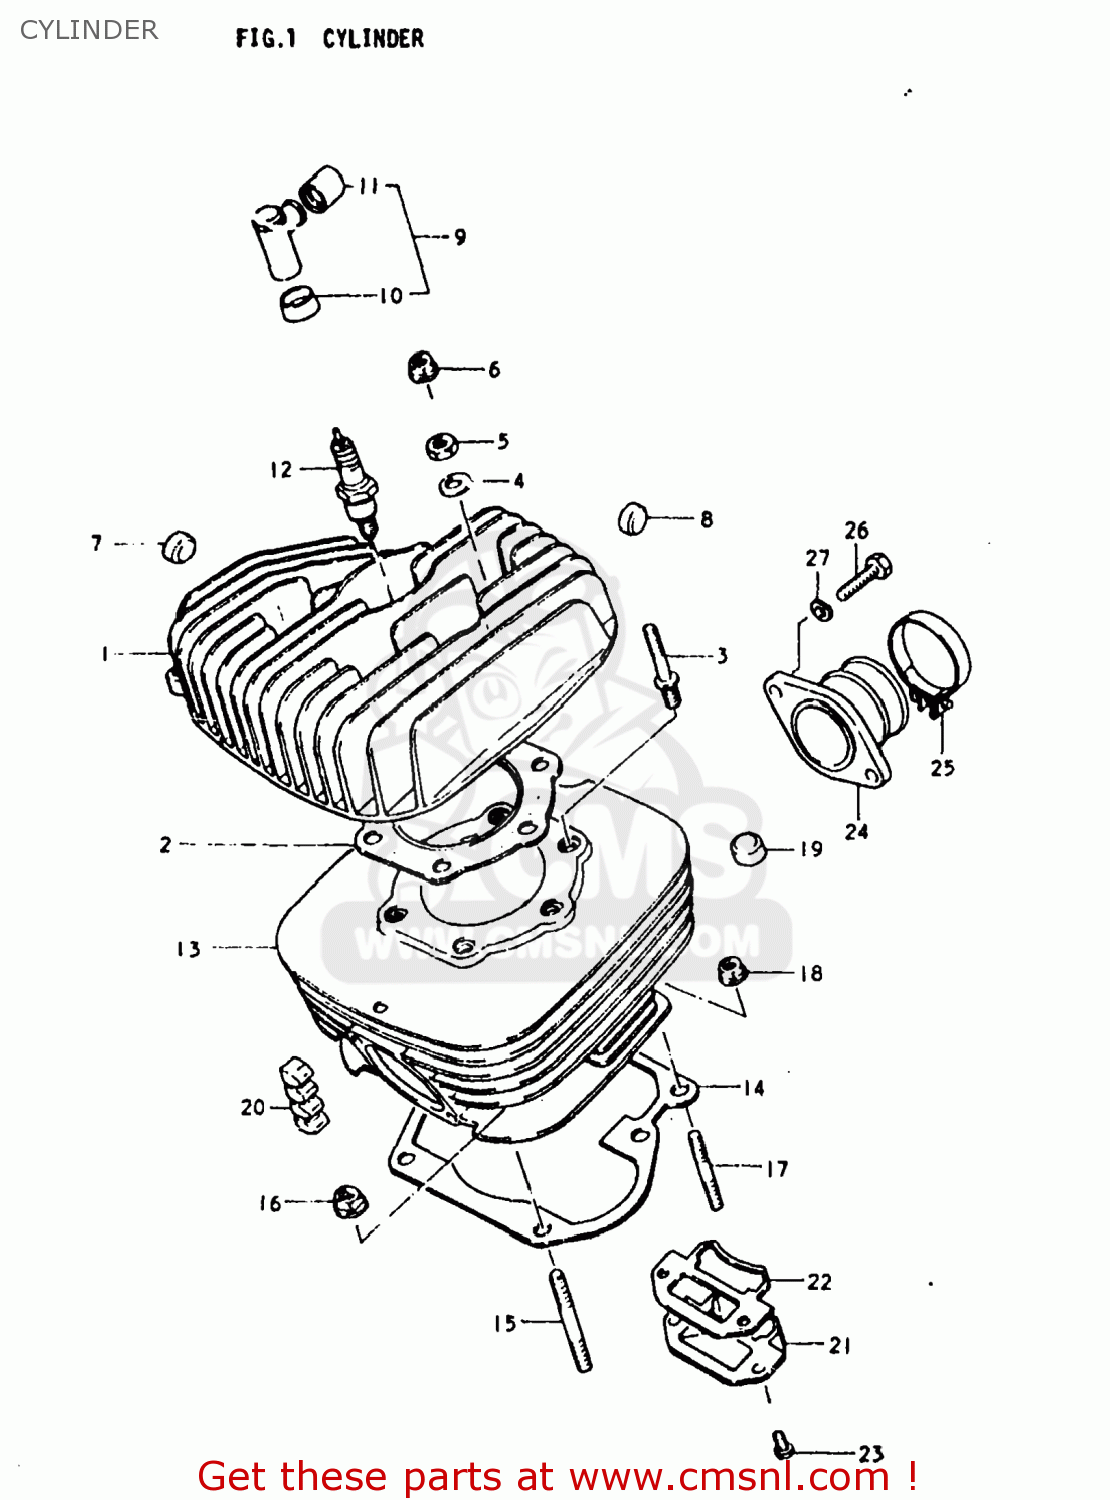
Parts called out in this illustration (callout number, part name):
1	HEAD,CYLINDER
2	GASKET,CYLINDER HEAD (NAS)
3	BOLT,STUD
4	WASHER
5	NUT (8MM)
6	NUT
7	PAD,CYLINDER
8	PAD,CYLINDER HEAD
9	CAP,SPARK PLUG
10	SEAL,SPARK PLUG
11	SEAL,SPARK PLU
12	PLUG,SPARK
13	CYLINDER
14	GASKET,CYLINDER (MCA)
15	STUD 10X25
16	NUT
17	STUD 8X25
18	NUT
19	PAD,CYLINDER HEAD
20	PAD,CYLINDER
21	VALVE ASSY,REED
22	GASKET,REED VALVE (MCA)
23	SCREW
24	PIPE,INTAKE
25	CLAMP
26	BOLT
27	LOCK WASHER
